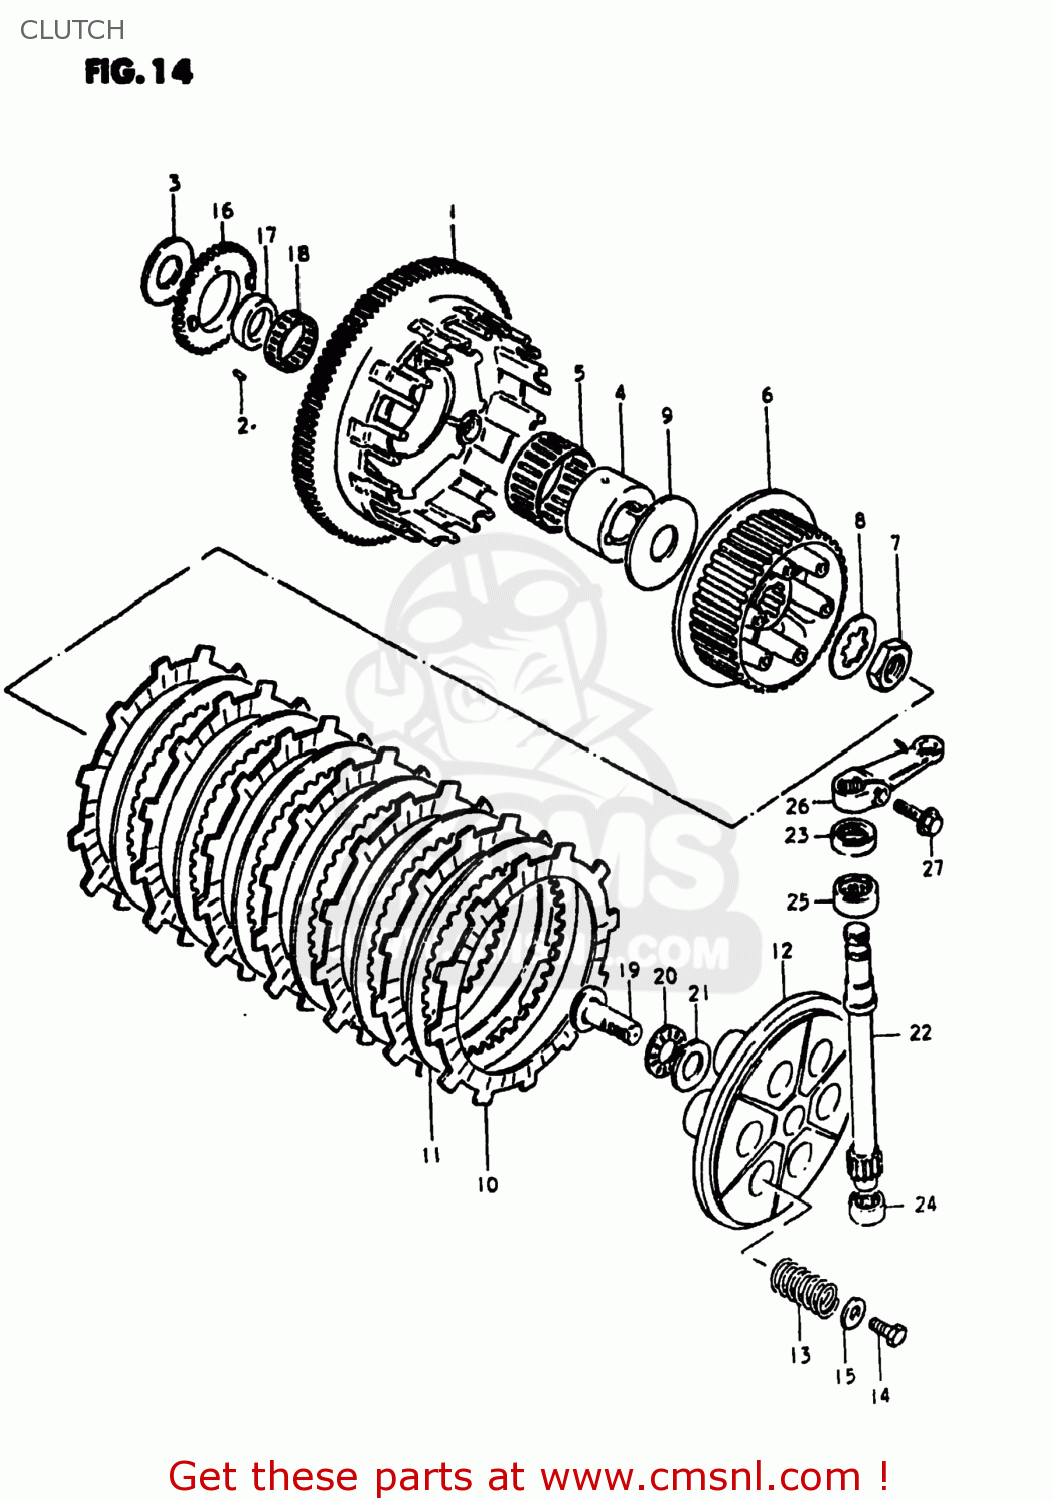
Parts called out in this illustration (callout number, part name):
1	GEAR ASSEMBLY,PRIMARY DRIVE
2	CUSHION,PRIMARY DRIVEN GEAR
3	WASHER
4	SPACER,PRIMARY DRIVEN
5	BEARING
6	HUB,CLUTCH SLEEVE
7	NUT
8	WASHER,LOCK
9	WASHER(25X66X3.5)
10	PLATE,CLUTCH DRIVE (MCA)
11	PLATE,CLUTCH DRIVEN
12	DISC,CLUTCH PRESSURE
13	SPRING
14	BOLT, UPPER
15	WASHER
16	GEAR,OIL PUMP DRIVE
17	SPACER,OIL PUMP DRIVE GEAR
18	BEARING(36X40X10)
19	RACK,CLUTCH RELEASE
20	BEARING(15X28X2)
21	WASHER
22	PINION,CLUTCH RELEASE
23	OIL SEAL
24	BEARING(12X19X12)
25	BEARING(15X22X12)
26	ARM,CLUTCH RELEASE
27	BOLT,REAR
